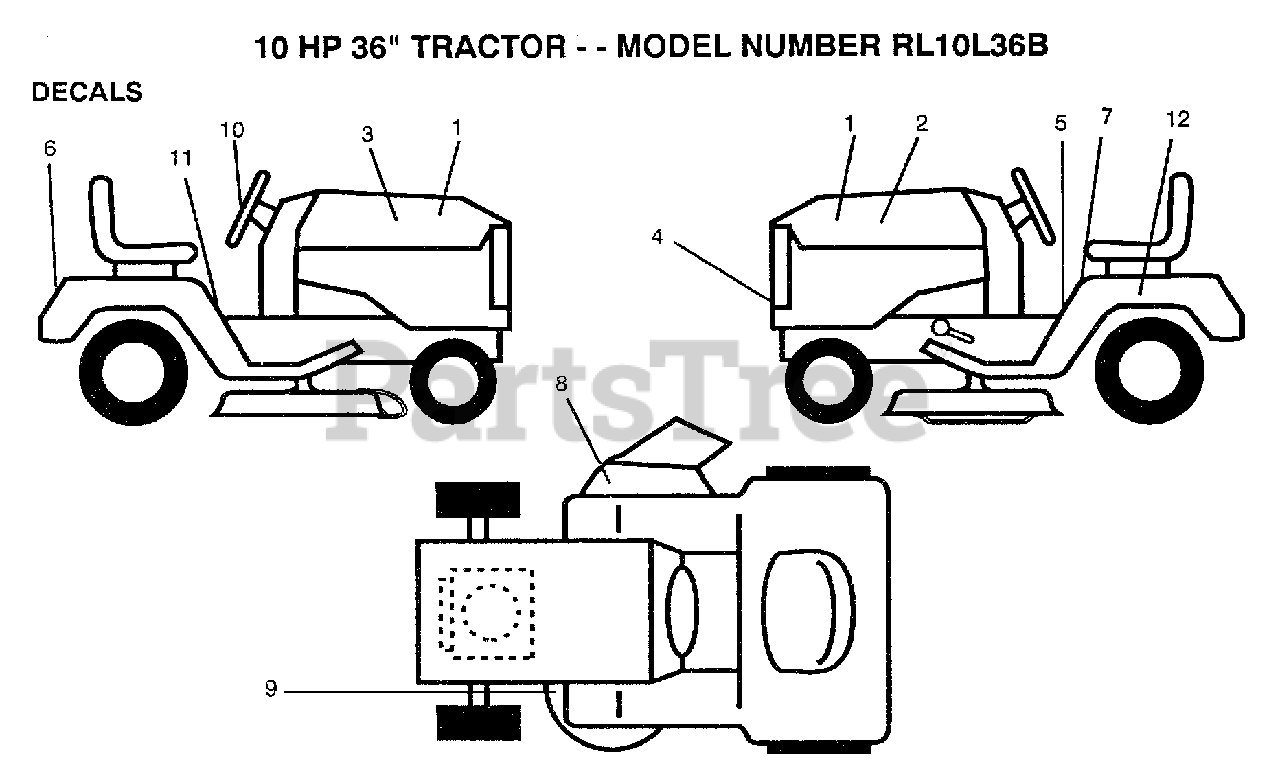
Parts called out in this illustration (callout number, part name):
4	GRILL DECAL
5	DECAL.FEND.QUICKS
6	FENDER DECAL
7	DECAL CAUTION
8	"DECAL, WARNING"
9	DECAL.V.BELT
10	"DECAL,STR WHL"
12	DECAL
